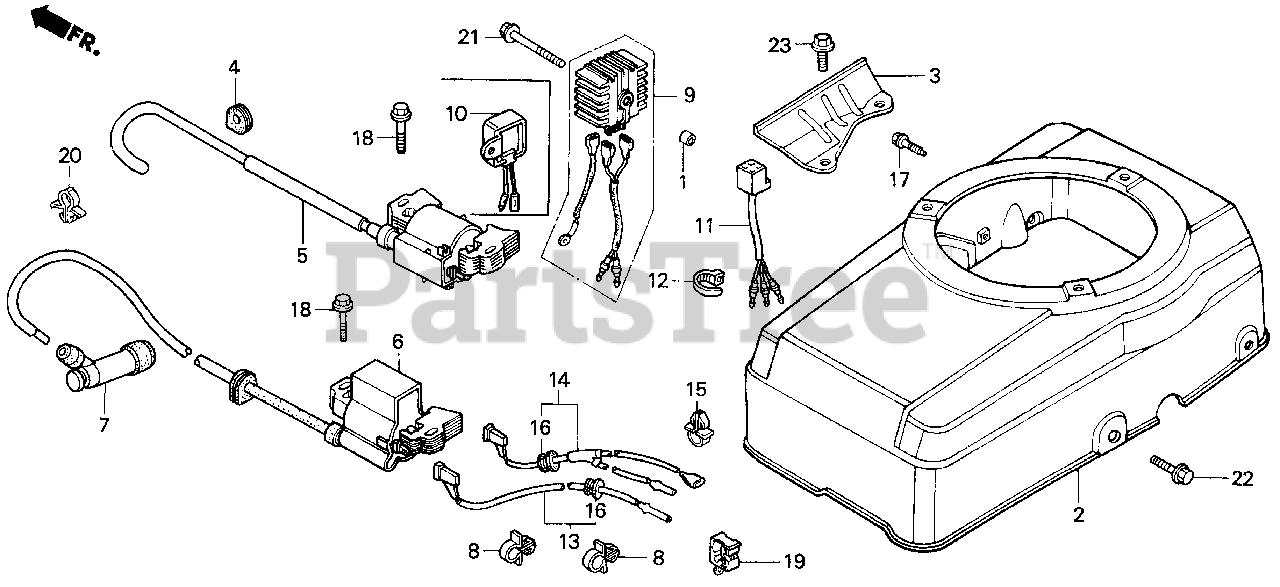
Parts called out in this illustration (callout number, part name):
1	SPACER, AIR CLEANER ELBOW
2	COVER, FAN *R8* (Honda Code 4542502). (BRIGHT RED)
2	COVER, FAN *NH246* (Honda Code 4498945). (LOOSY GRAY)
2	COVER, FAN *T36* (Honda Code 4498952). (BUNTON YELLOW)
2	COVER, FAN *R8* (Honda Code 7567951). (BRIGHT RED)
4	GROMMET, WIRE
5	COIL ASSY., IGNITION
7	CAP ASSY., NOISE SUPPRESSOR
8	CLIP, IGNITION WIRE (8MM)
9	RECTIFIER ASSY., SILICON
12	BAND B1, CABLE
14	WIRE, STOP SWITCH
16	GROMMET, WIRE
17	BOLT, FLANGE (6X12) (CT200)
18	BOLT, FLANGE (6X28)
21	BOLT, FLANGE (6X40)
